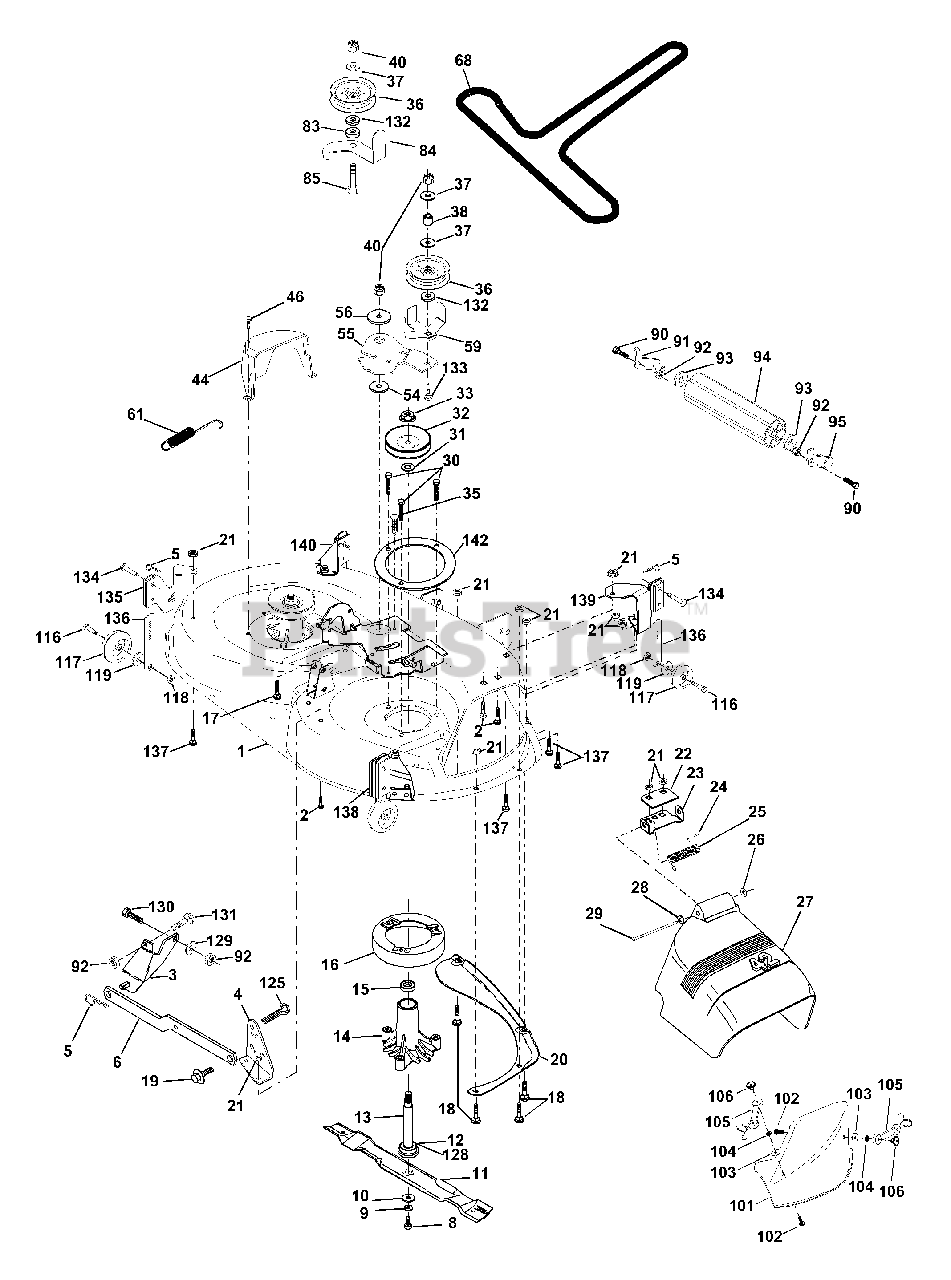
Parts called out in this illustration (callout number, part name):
1	Deck Weldment Mower 42" W/Adj
2	Bolt Rdhd Sqnk 5/16-18unc X3/4
3	Bracket Asm Fr Sway Bar 38/42
4	Bracket Asm Deck 42"sway Bar
5	Retainer Spring
6	Arm Suspension Rear
8	Bolt 3/8-24x1 25 Gr8 Patched
9	Washer Lock Hvy 3/8 Unplated
10	Washer Hard Blade Mower Vented
11	Blade Mower Mulching 42"
12	Bearing Ball #6204 (Mandrel)
13	Shaft Asm W/lower Bearing
14	Housing Mandrel Vented (machd)
15	Bearing Ball Mandrel
16	Stripper Round Mower
17	Bolt Rdhd Sqnk 3/8-16 X 2-1/4
18	Bolt Carr 5/16-18 X 5/8
19	Bolt Shoulder
20	Baffle Vortex 42
21	Nut Crown Lock 5/16-18
22	Stiffener Bracket 42" deck
23	Bracket Deflector Mower 42"
24	Cap Sleeve 80x 112 Blk Mower
25	Spring Torsion Deflector 2 52
26	Nut Push Phos & Oil
27	Shield Deflector Mower 42" Grey
28	Washer 11/32 X 5/8 X 16 Ga
29	Rod Hinge 42"6 75 Wlg
30	Screw Thdrol Washer Head
31	Washer Spacer Mower Vented
32	Pulley Mandrel 42"
33	Nut 9/16top Lock Flng Cntr
35	Fastener Christmas Tree
36	Pulley Idler Flat 3 060
37	Washer 13/32 X 13/16 X 16 Ga
38	Spacer Spring Stop Idler
40	Nut Lock 3/8-16 Unc
44	Guard Mandrel LH Black
46	Screw Thdrol 1/4-20x5/8
54	Washer Hardened
55	Arm Idler 42" mower LT/YT
56	Spacer Retainer Mower
59	Guard, Belt
61	Spring Ext. Elect
68	V-Belt Mower
83	Washer Sintered
84	Keeper Belt Idler
85	Bolt Carriage 3/8-16 x 2-1/2 Gr.5
90	Bolt Fin Hex 3/8-16unc X 1
91	Bracket Asm Noseroller LH
92	Nut Lock Hex w/ins. 3/8-16 UNC
93	Washer 17/32 X 7/8 X 16 Ga
94	Roller Nose 38 & 42
95	Bracket Asm Noseroller RH
101	Cover Mulching 42" Blk
102	Screw
103	Washer #10
104	Washer Lock #10
105	Latch Asm Bagger
106	Nut Weld .327/.304 #10-24
116	Bolt Shld
117	Wheel Gauge blk.
118	Nut Centerlock 3/8 - 16 UNC
119	Washer 3/8 x 7/8 x 14 Ga.
125	Cotter Pin
128	Washer Felt
129	Washer 13/32 x 13/16 x 12 Ga.
130	Bolt Fin Hex 3/8-16 UNC x 1 Gr. 5
131	Bolt Rdhd Sqnk 3/8-16 Unc x 1
132	Washer 13/32 x 1-3/8 x 3 Ga
133	Bolt Rdhd 3/8-16 UNC x 2-3/4 Gr.5
134	Pin Head Rivet
135	Bracket Asm Whl Ga Rear LH 42"
136	Bar Pnt Adjusting Wheel Gauge
137	Bolt Carr 5/16-18 x 5/8 Short
138	Bracket Asm Whl Ga. Rear RH 42"
139	Bracket Asm Whl Ga. Front RH 42"
140	Bracket Asm Whl Ga. Front RH 42"
142	Reinforcement Mandrel Ring
